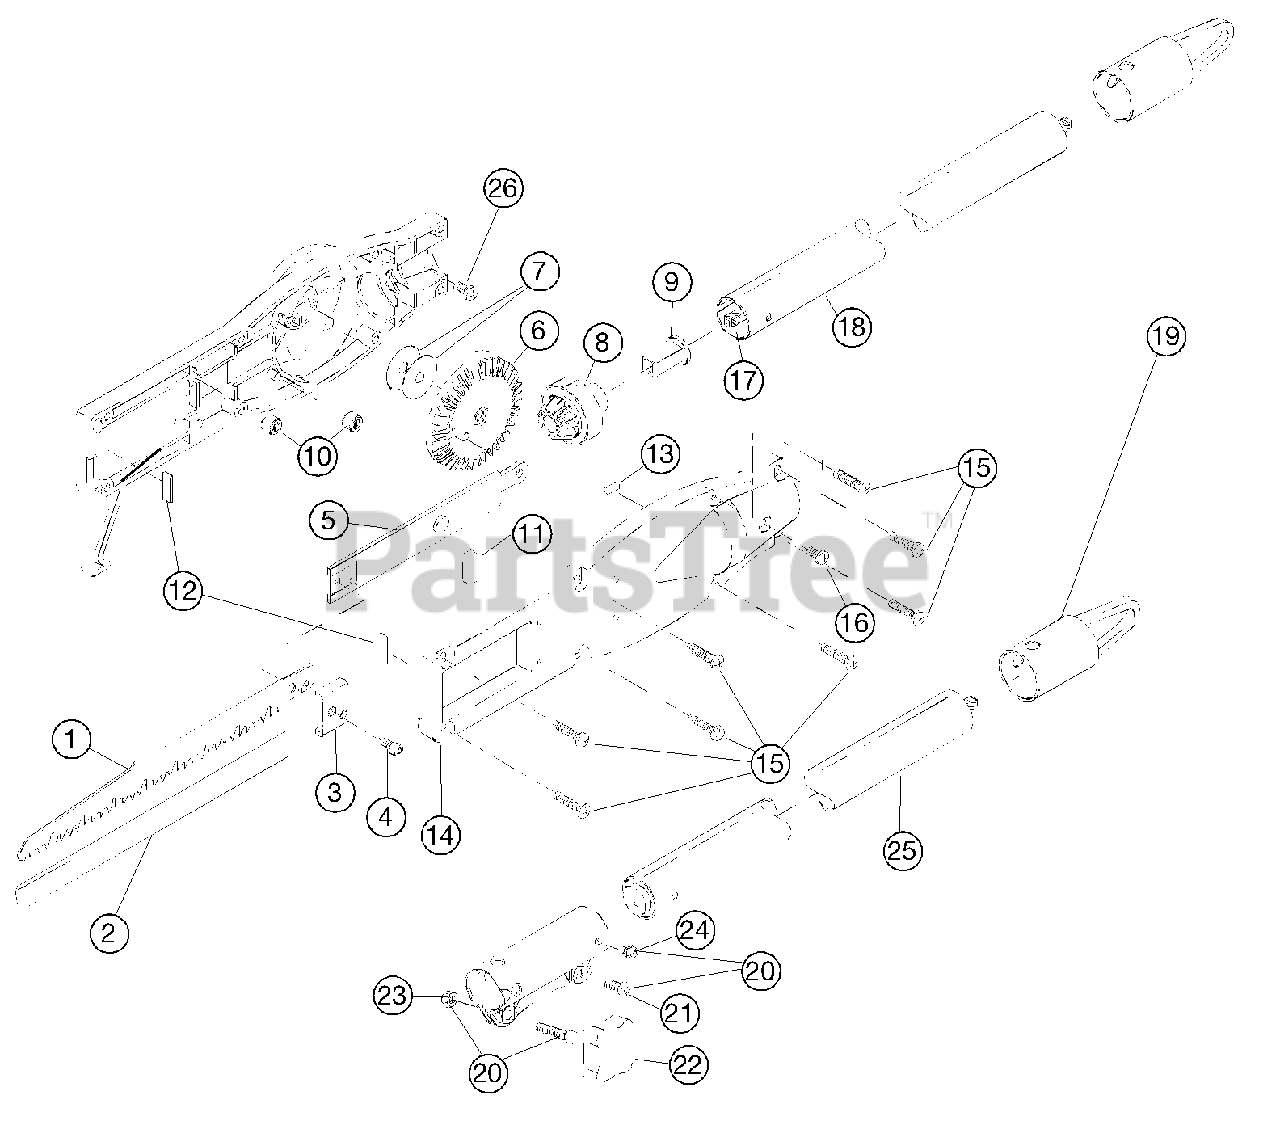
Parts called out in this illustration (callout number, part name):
1	Blade (2 pack)
2	Blade Cover
3	Blade Clamp
4	Blade Clamp Screw and Washer Assembly
5	Arbor Assembly
6	Bevel Gear
8	Pinion Bevel Gear
9	Insulator
10	Slide Bushing
11	Felt Seal
12	Slider (2-pack)
13	Rubber Plug
14	Housing set
15	Housing Screw
16	Anti-Rotation Screw
17	Drive Shaft Assembly
18	Drive Shaft Housing Assembly
19	Hanger
20	Coupler
22	Adjustment Knob
23	Knob Retaining Nut
25	Extension Boom and Flex Shaft Assembly
26	Anti-Rotation Screw
